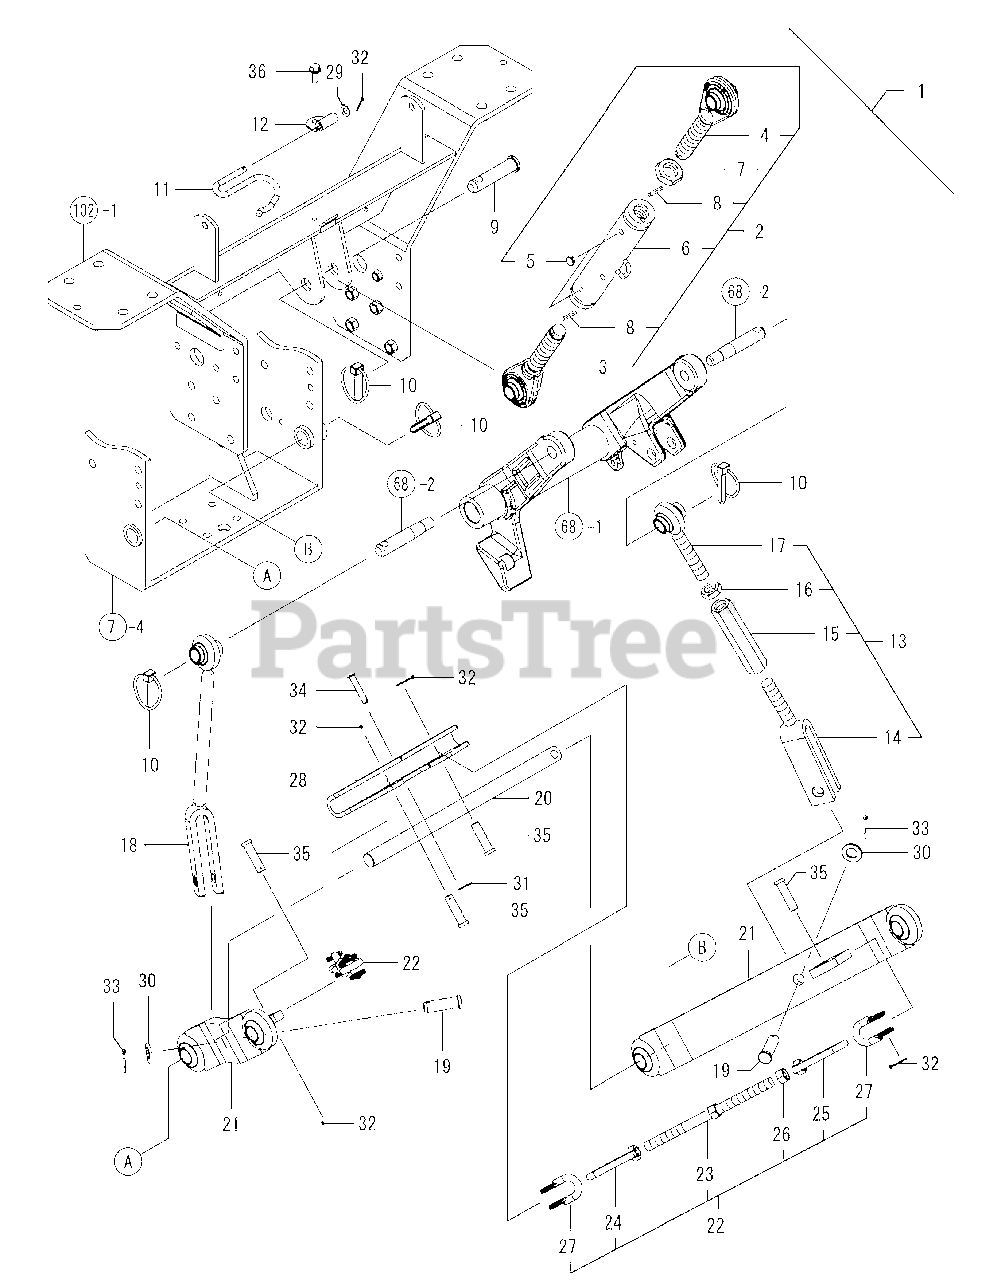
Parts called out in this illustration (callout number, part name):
1	3P LINK KIT
3	EYE BOLT L CMP
4	EYE BOLT R CMP
6	TURNBACKLE ASSY
7	TURN BACKLE CMP
9	PIN, UPPER LINK
10	PIN ASSY, LINTCH
12	PLATE (TOPLINK)
13	ROD CMP, LIFT R
14	END ASSY, LOWER
17	END ASSY, UPPER
18	ROD CMP, LIFT L.H.
20	BAR, LOWER LINK
21	LINK ASSY, LOWER
22	CHAIN ASSY, CHECK
23	TURNBACKLE ASSY
24	EYENUT, CHAIN L
25	EYENUT, CHAIN R
35	PIN, 12 X 40
